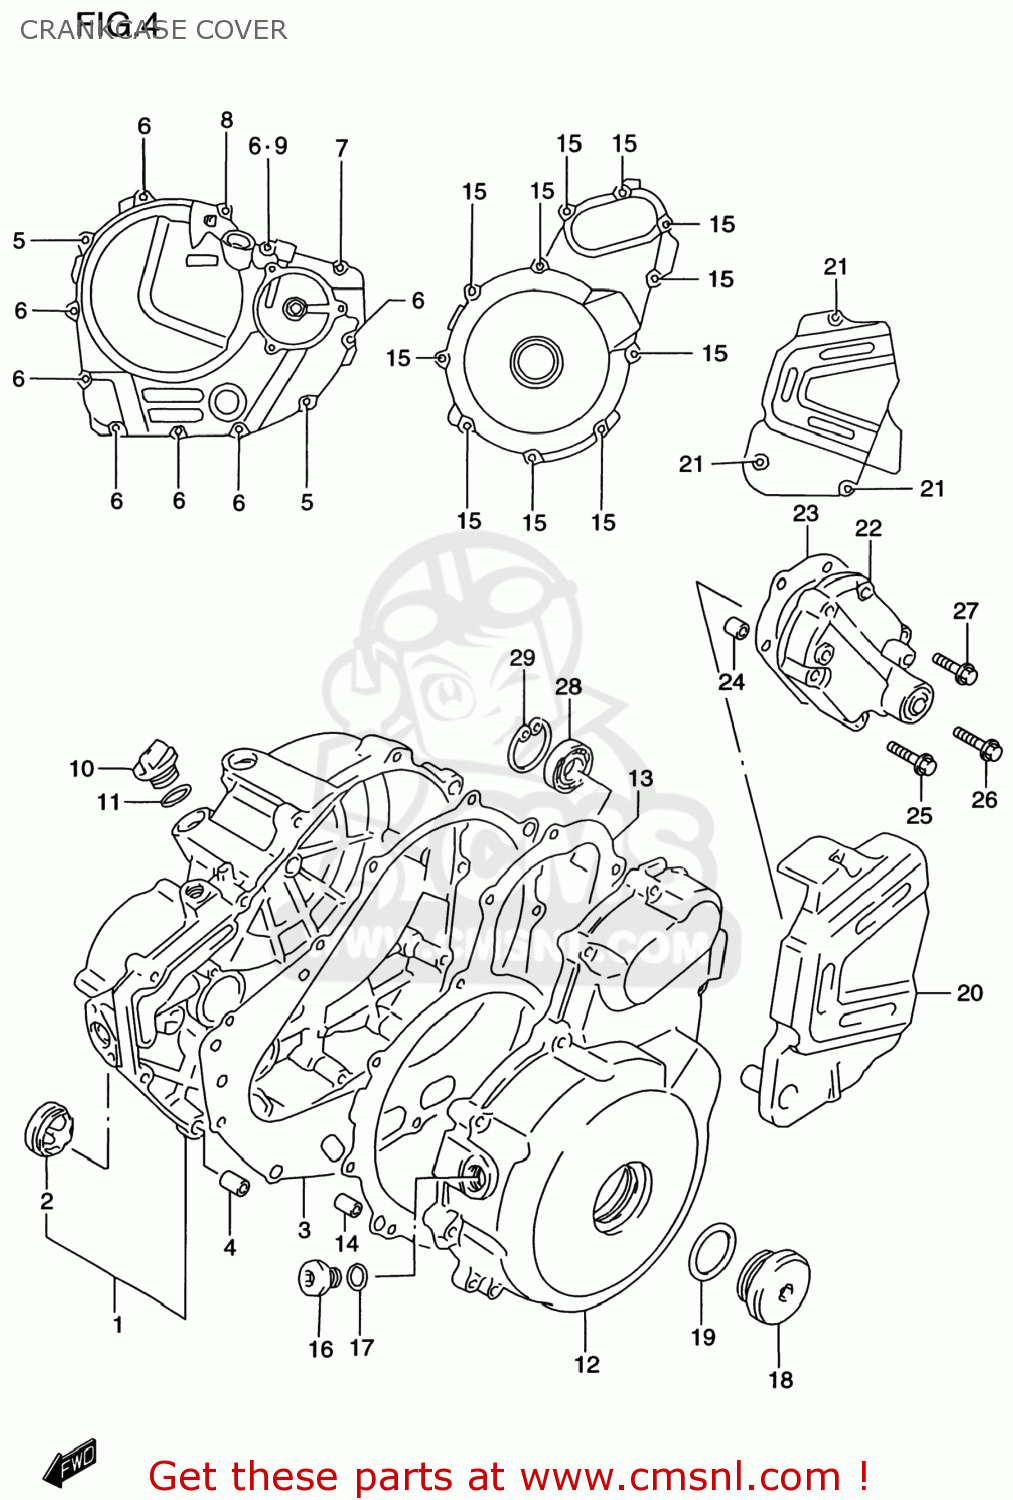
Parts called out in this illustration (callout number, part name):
1	COVER,CLUTCH
2	LENS,OIL LEVEL CHECK
3	GASKET,CLUTCH COVER
4	PIN
5	BOLT
6	BOLT
7	BOLT
8	BOLT
9	GASKET(5.8X11X1.2) (NAS)
10	PLUG
11	O RING(D:3.1,ID:16.8)
12	COVER,MAGNETO
13	GASKET,MAGNETO COVER
14	PIN
15	BOLT
16	PLUG,14X12
17	GASKET(13.8X18.8X4.8) (NAS)
18	PLUG(SILVER)
19	O RING(D:3.1,ID:32.7)
20	COVER,ENGINE SPROCKET
21	BOLT
22	COVER,GEAR SHIFT
23	GASKET,GEAR SHIFT COVER (NAS)
24	PIN
25	BOLT
26	BOLT,G/S SWITC
27	SCREW
28	BEARING(12X28X8)
29	CIRCLIP
